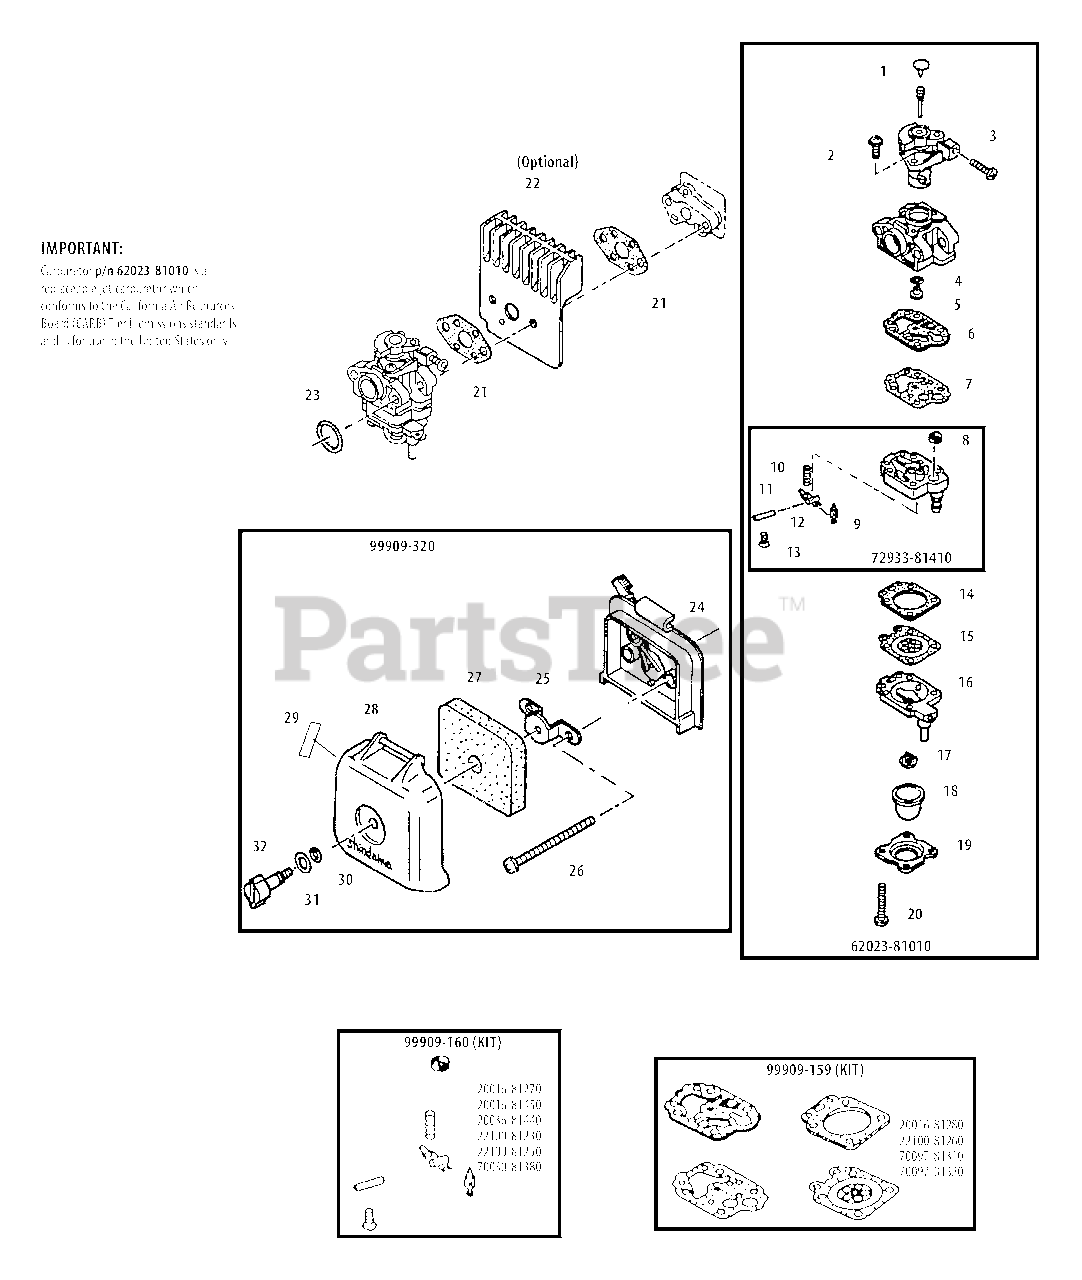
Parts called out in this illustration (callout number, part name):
1	PLUG
2	SCREW, THROTTLE COLLAR
3	THROTTLE VALVE ASSY
4	O-RING
5	JET, MAIN
6	GASKET, PUMP
7	DIAPHRAGM, PUMP
8	SCREEN, FUEL INLET
9	VALVE, INLET NEEDLE
10	SPRING, METERING LEVER
11	LEVER, METERING
12	PIN, METERING LEVER
13	SCREW
14	GASKET, METERING DIAPHRAGM
15	DIAPHRAGM, METERING
16	BODY ASSY, PURGE
17	VALVE, CHECK
18	BULB, PURGE
19	RETAINER, PURGE BULB
20	SCREW
21	GASKET, CARBURETOR
22	DEFLECTOR, HEAT
23	O-RING 15
24	CASE, AIR FILTER
25	BRACKET
26	SCREW - 5×67
27	FILTER, AIR
28	COVER, AIR FILTER
29	LABEL, CHOKE
30	O-RING
31	WASHER, CONE M6
32	THUMBSCREW
62023-81010	CARBURETOR
72933-81410	BODY ASSY, PUMP
99909-159	GASKET / DIAPHRAGM KIT
99909-160	VALVE KIT, INLET NEEDLE
99909-320	AIR FILTER ASSY
